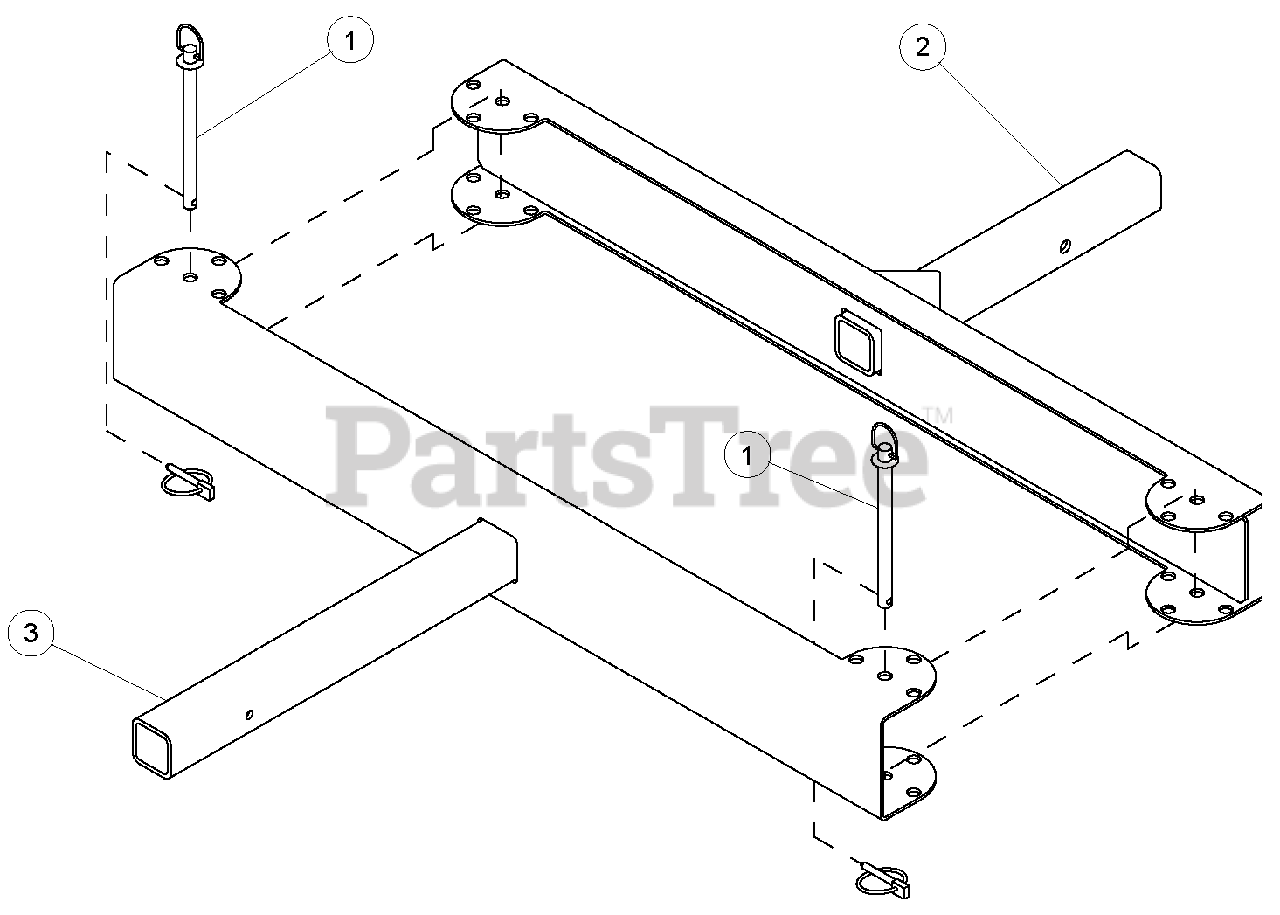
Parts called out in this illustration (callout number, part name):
1	PIN, HITCH 1/2 X 6-1/2 W LYNCH
2	WELDMENT, SWING AWAY
3	WELDMENT, SWING AWAY
